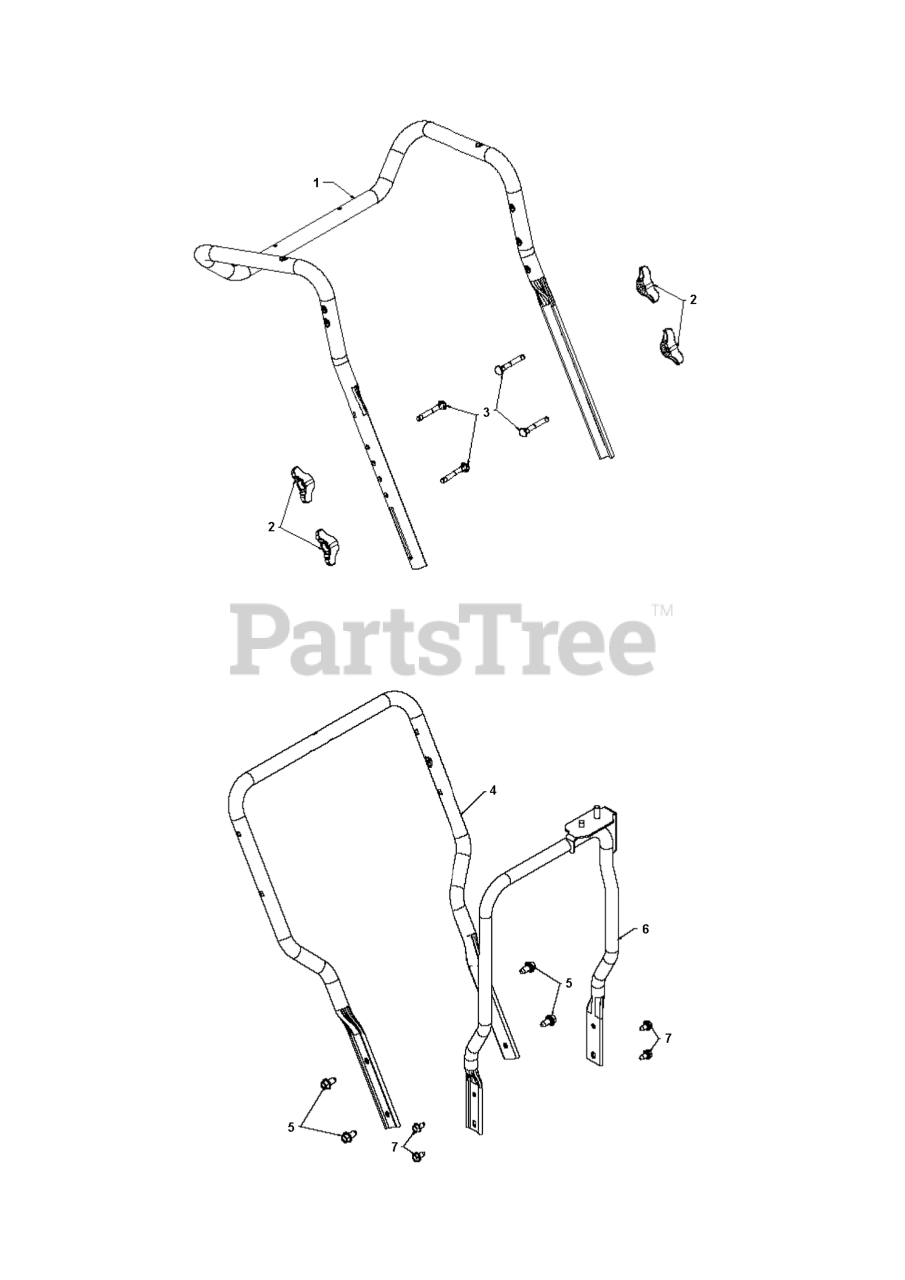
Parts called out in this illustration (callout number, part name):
1	HANDLE.UPPER.SNOW.GREY
1	HANDLE.UPPER.498
2	HANDLE.KNOB.BLACK
3	BOLT.CARRIAGE.5/16-18 X 2.25
3	BOLT, HANDLE 5/16-18X1.75
4	HANDLE.LOWER.498
4	HANDLE LOWER,GRAY,MS498
5	SCREW, 3/8-16X3/4
6	SUPPORT WELDMENT, CHUTE PAINTE
6	SUPPORT.ASM.CHUTE.ROTATOR.BLAC
7	BOLT.5/16HEX.WHS.HD
